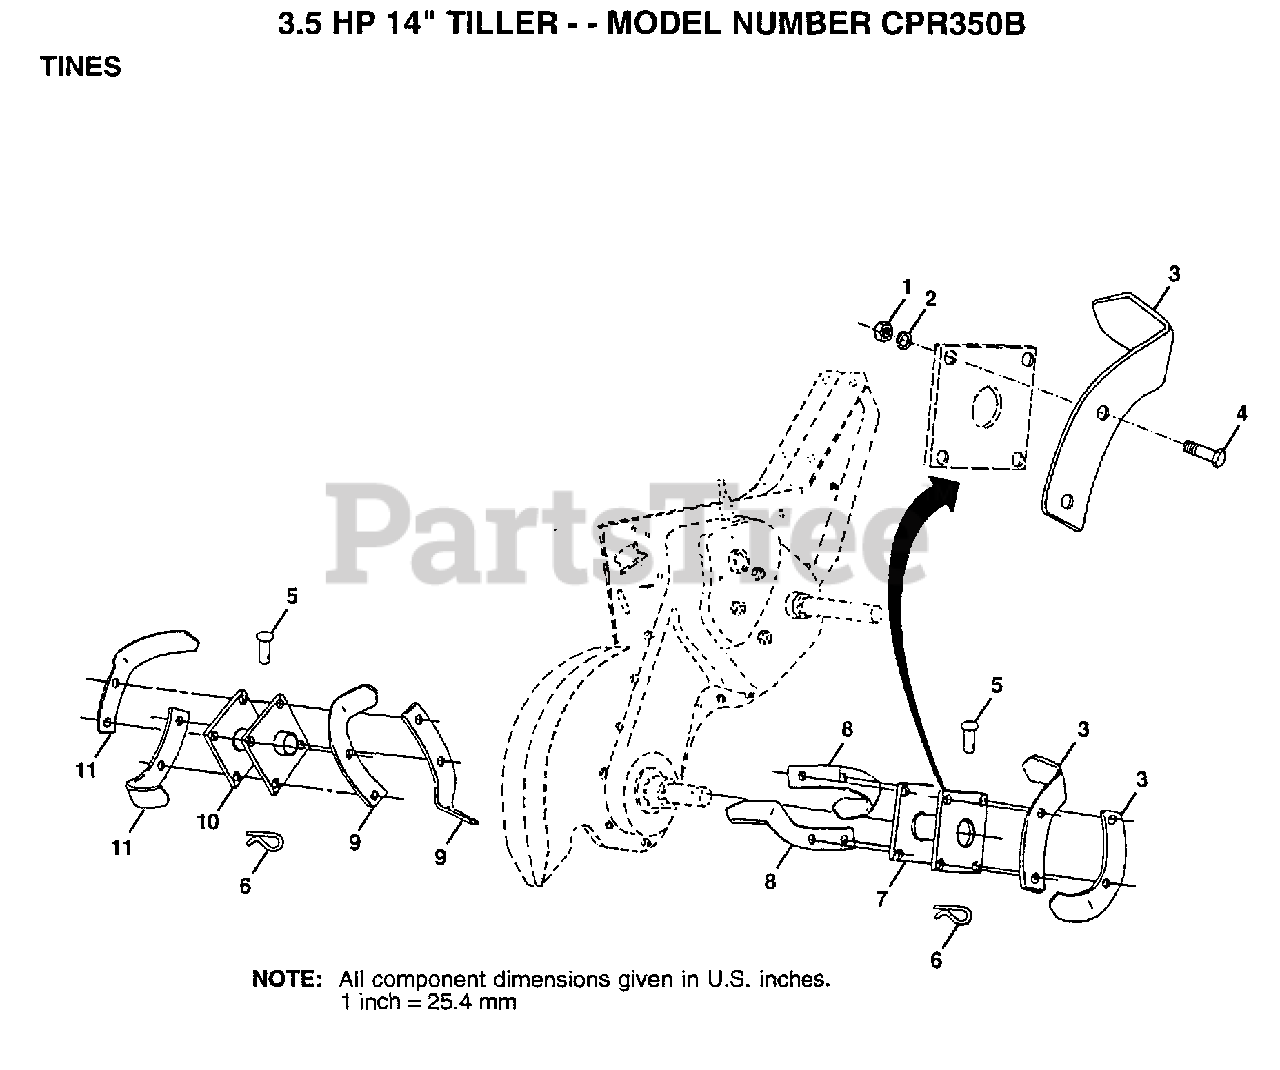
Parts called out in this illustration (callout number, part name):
2	LOCKWASHER
4	BOLT
5	PIN.CLEVIS.SHEAR
6	RETAINER.SPRING
7	ASM HUB&PLATE RH
8	"TINE.RH.12"""
9	"TINE.LH.12"""
10	ASM HUB&PLATE LH
